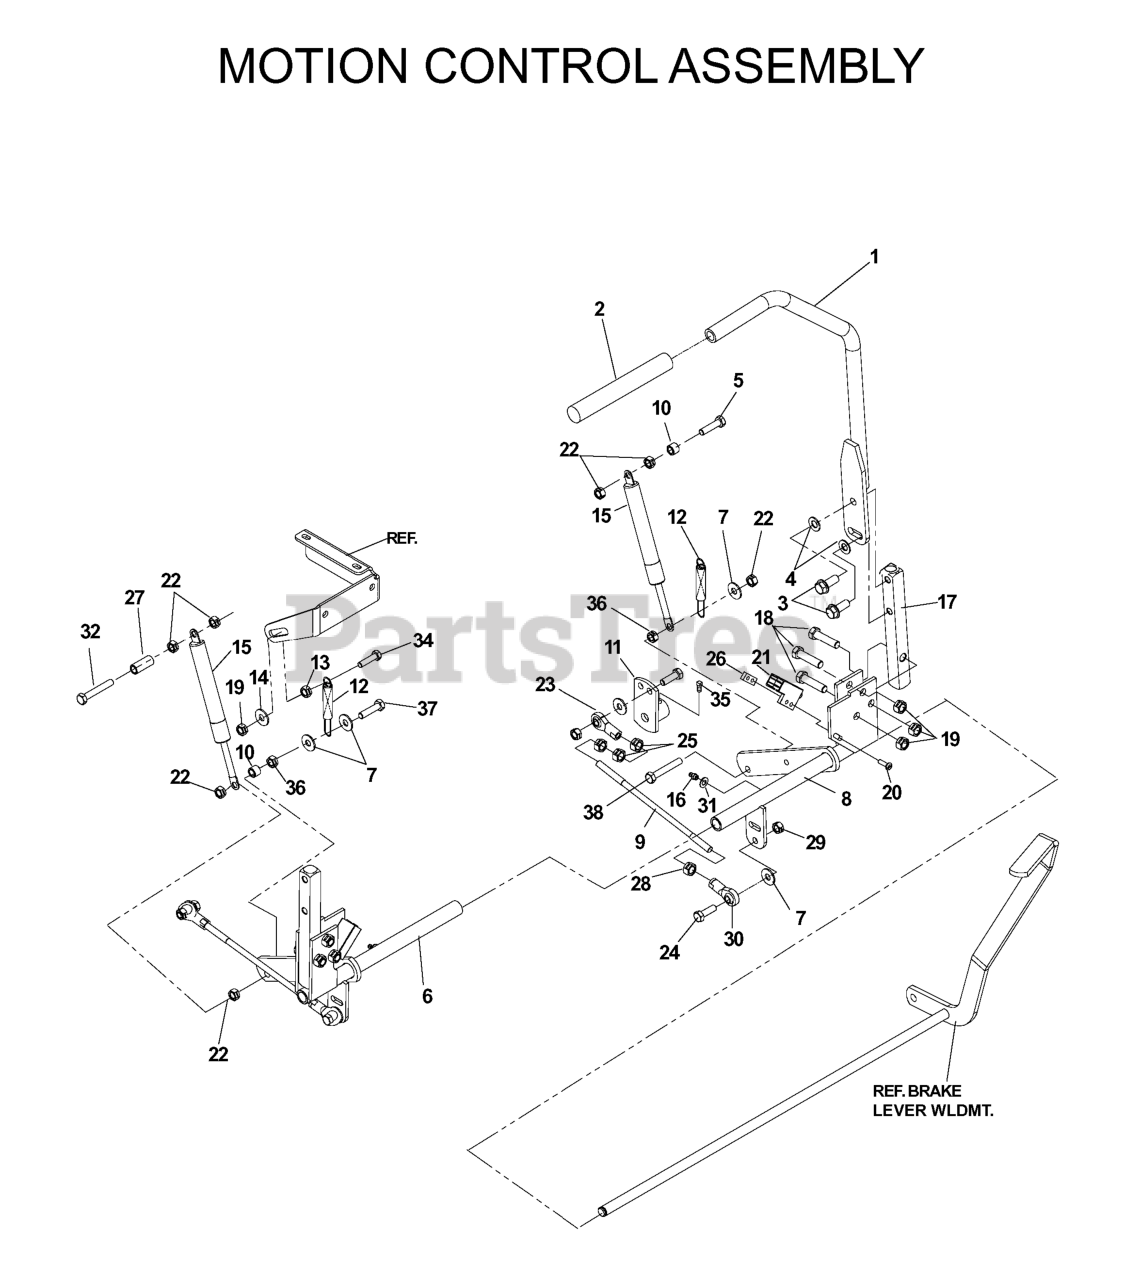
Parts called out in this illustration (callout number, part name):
1	HANDLE ASM
2	GRIP, PARK BRAKE
3	HCS 3/8-16X1.GRD.5.ZD
4	WASHER, 3/8 DISC SPRING SPEC
5	CAPSCREW 5/16 X 1/1/2 HEX HEAD
6	CONTROL WLDMNT RH
7	WASHER 5/16 FLAT
8	CONTROL WLDMNT - LH
9	PUMP CONTROL LINK
11	PUMP LEVER
13	NUT 3/8C WHIZ
14	WASHER 3/8 FLAT
16	ZERK
17	CONTROL ARM
18	HCS 3/8-16 X 1 3/4 GR5
19	NUT 3/8-16 NYLOC
20	SCREW #10-24 X 5/8
21	SWITCH, INTERLOCK
22	NUT 5/16C CENTERLOCK
23	BALL JOINT, RIGHT HANDED
24	HCS 5/16C X 1 1/4
26	TAPPED PLATE
28	NUT 5/16F LEFTHAND
29	NUT 5/16 NYLOC
30	BALL JOINT, LEFT HANDED
32	HCS 5/16-18X2
33	HCS 3/8C X 3
34	HCS 3/8C X 2 1/2
35	5/16C X 5/8 "V" POINT
36	NUT 5/16C WHIZ
37	TAP BOLT 5/16C X 2 1/4
38	BOLT, TAP 5/16-18
